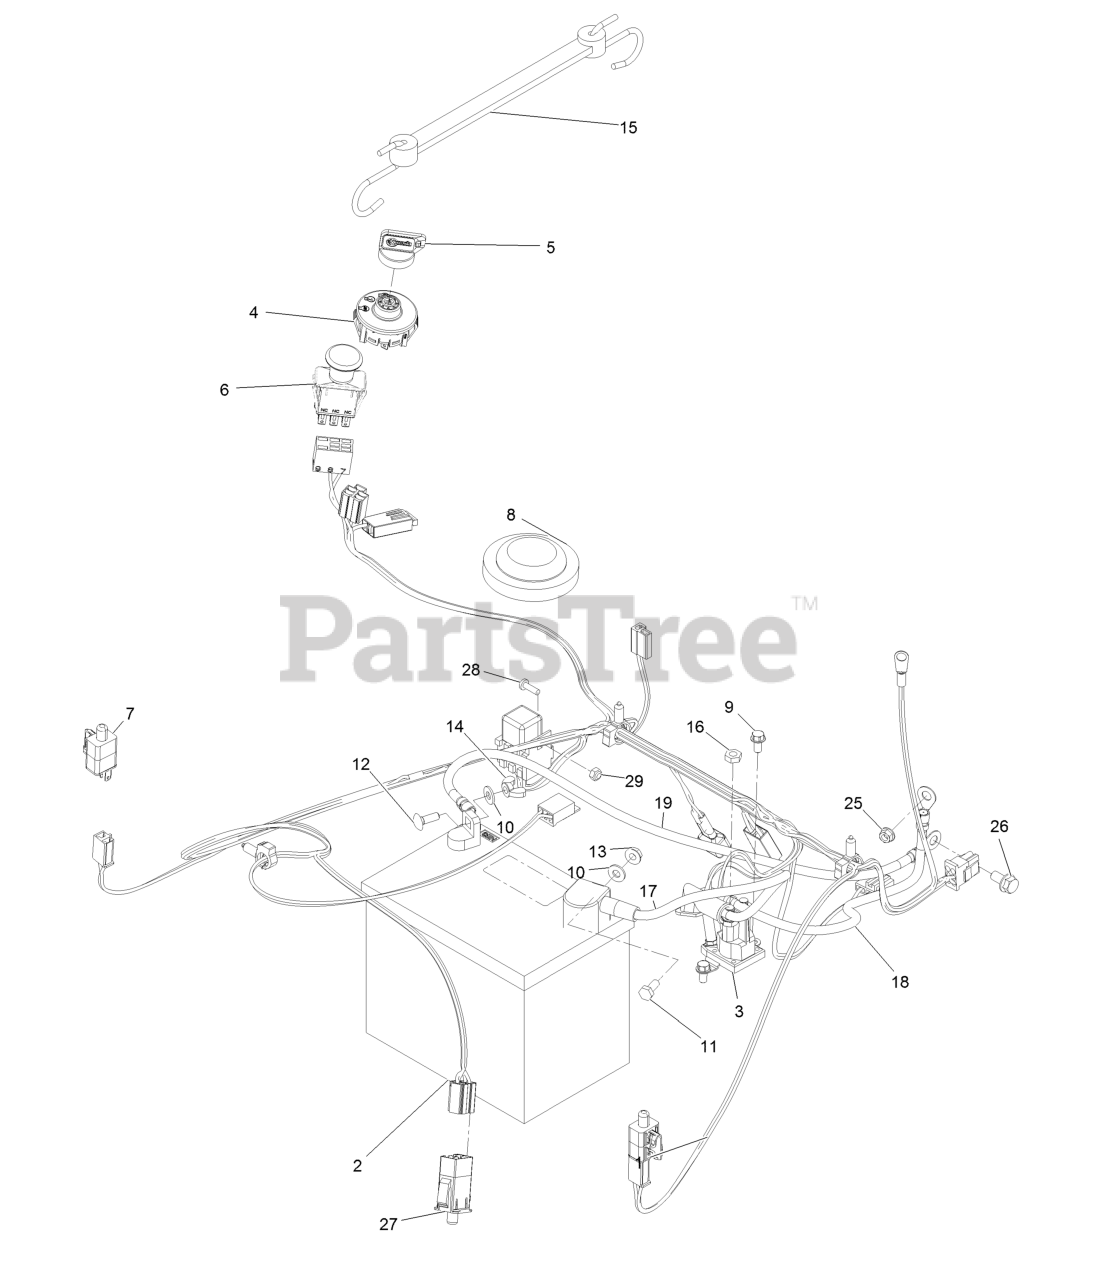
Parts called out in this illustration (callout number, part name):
1	HARNESS-WIRE
2	BATTERY
3	SOLENOID
5	KEY-IGNITION
6	SWITCH-PTO
8	SWITCH-SEAT
9	SCREW-HWH
10	WASHER-FLAT
11	SCREW-HH
12	BOLT-CARR
14	NUT-WING
15	HOLDDOWN-BATTERY
16	NUT-JAM
17	CABLE-BATTERY, RED
18	CABLE-BATTERY, POSITIVE
19	CABLE-BATTERY, BLACK
26	SCREW-HHF
27	SWITCH-DELTA
28	SCREW-PPH
29	NUT-LOCK, NI
